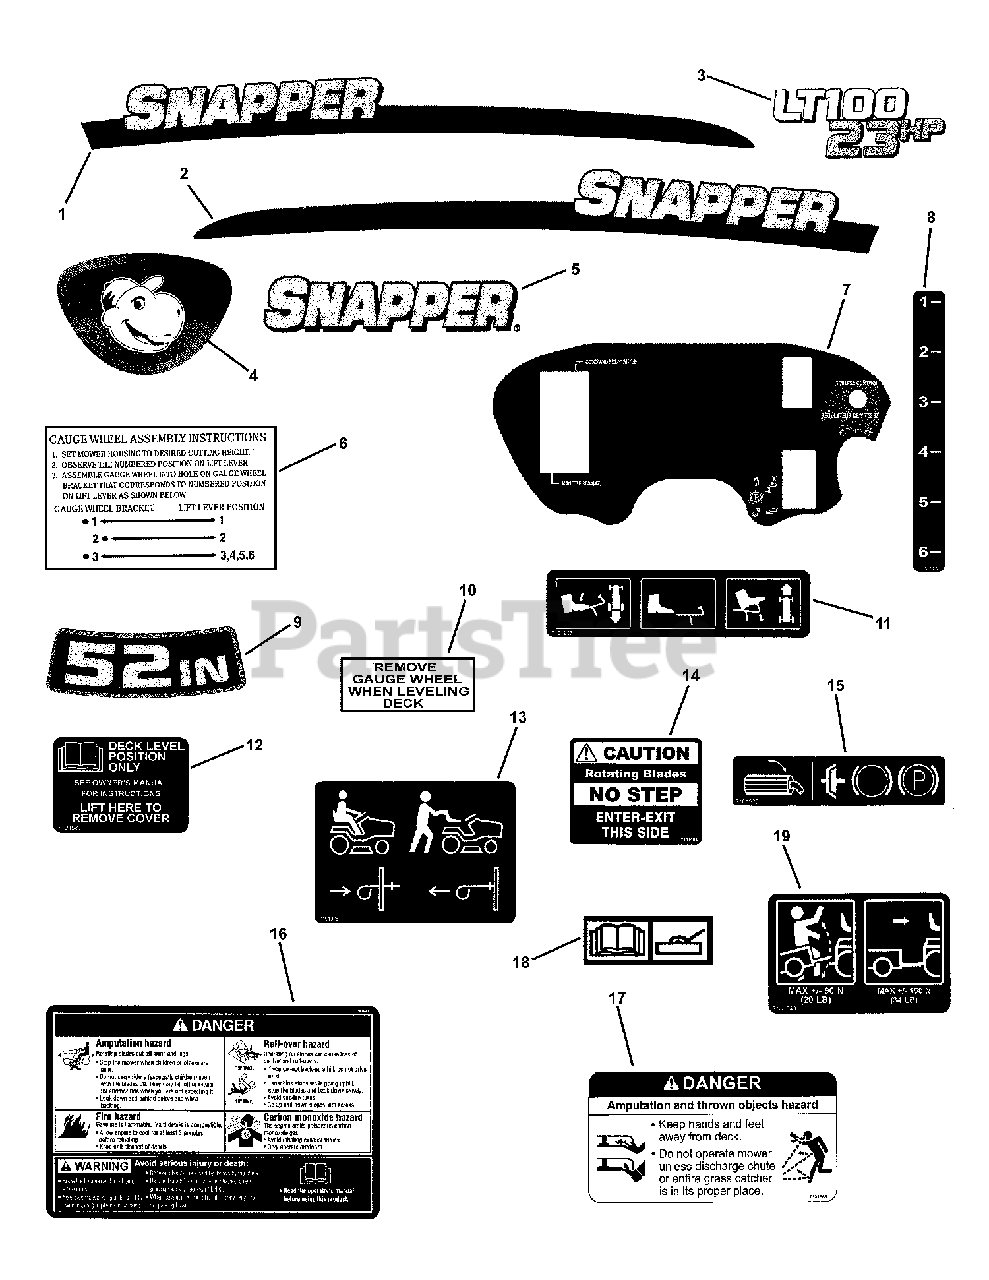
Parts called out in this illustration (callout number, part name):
1	DECAL, Snapper Name Plate, RH
2	DECAL, Snapper Name Plate, LH
3	DECAL, 23 hp
4	DECAL, Snapper Logo, Steering Wheel
5	DECAL, Snapper Logo, Rear
6	DECAL, Gage Wheel Instruction
7	DECAL, Snapper Dash Panel
8	DECAL, Height of Cut
9	DECAL, 52 Deck
10	DECAL, Gage Wheel Leveling
11	DECAL, Drive Pedal
12	DECAL, Deck Level
13	DECAL, Roll Release
14	DECAL-No Step
15	DECAL, Belt/Clutch
16	DECAL-Umber
17	DECAL, Danger Do Not Operate w/o Deflector
18	DECAL, Deck Level
19	DECAL, Weight Limitation
